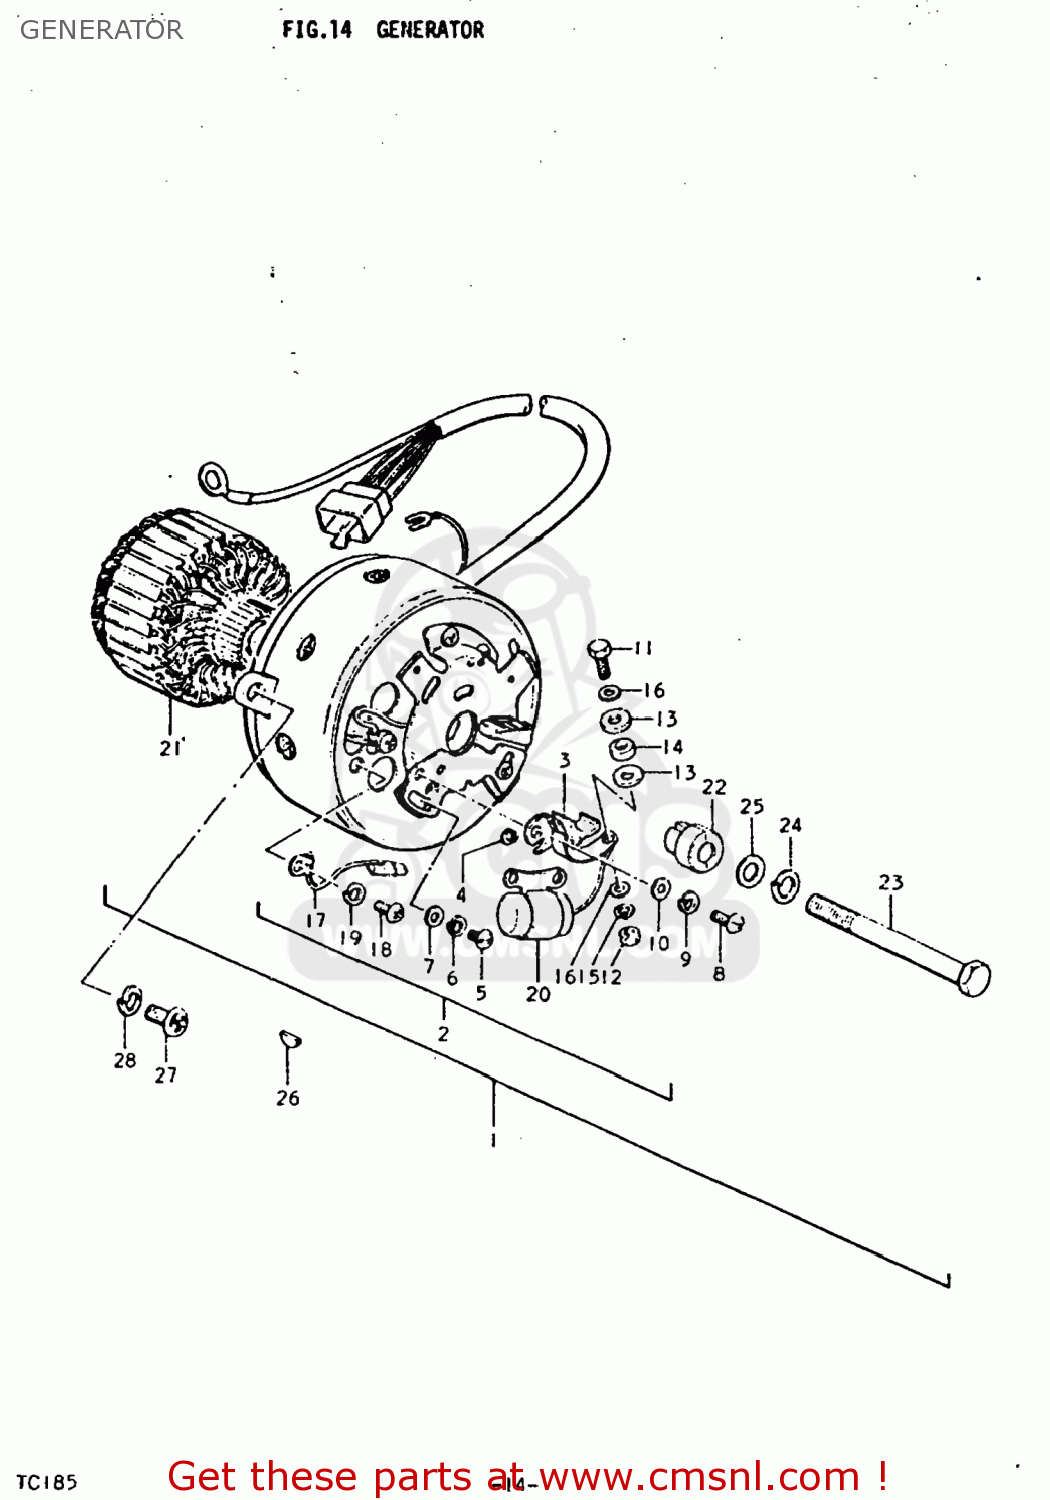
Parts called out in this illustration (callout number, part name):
1	ALTERNATOR ASSEMBLY
2	STATOR ASSEMBLY
3	POINT ASSY,CONTACT LH
4	ADJUSTER,CONTACT POINT
5	SCREW
6	LOCK WASHER
7	WASHER
8	SCREW
9	LOCK WASHER
10	WASHER
11	BOLT, POINT TERMINAL
12	NUT
15	LOCK WASHER
16	WASHER
17	BRUSH,CARBON
18	SCREW
19	LOCK WASHER
20	CONDENSER
21	ARMATURE (ASB)
22	CAM,CONTACT BREAKER
23	BOLT
24	LOCK WASHER
25	WASHER
26	KEY 4MM
27	SCREW
28	LOCK WASHER
